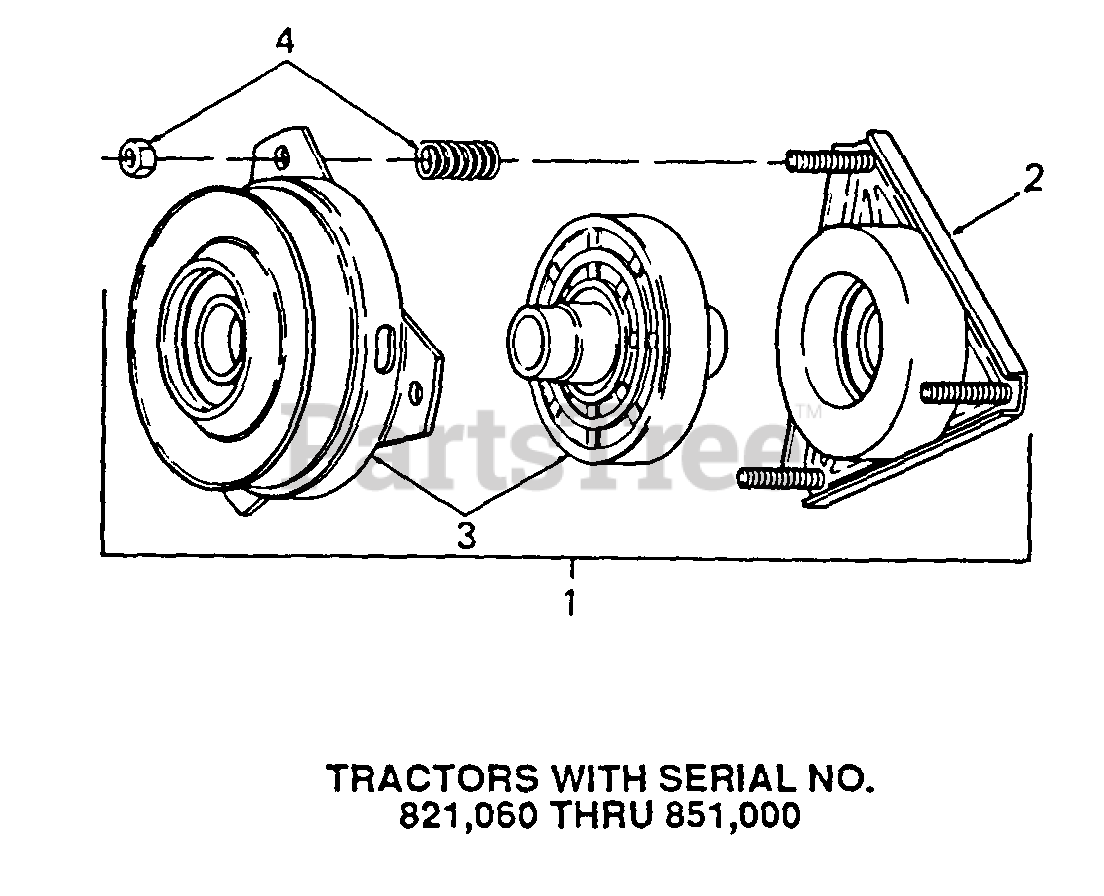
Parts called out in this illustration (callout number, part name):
1	Clutch Assy, PTO
2	Field Assy
3	Kit, Rotor & Armature
4	Mounting Accessories
